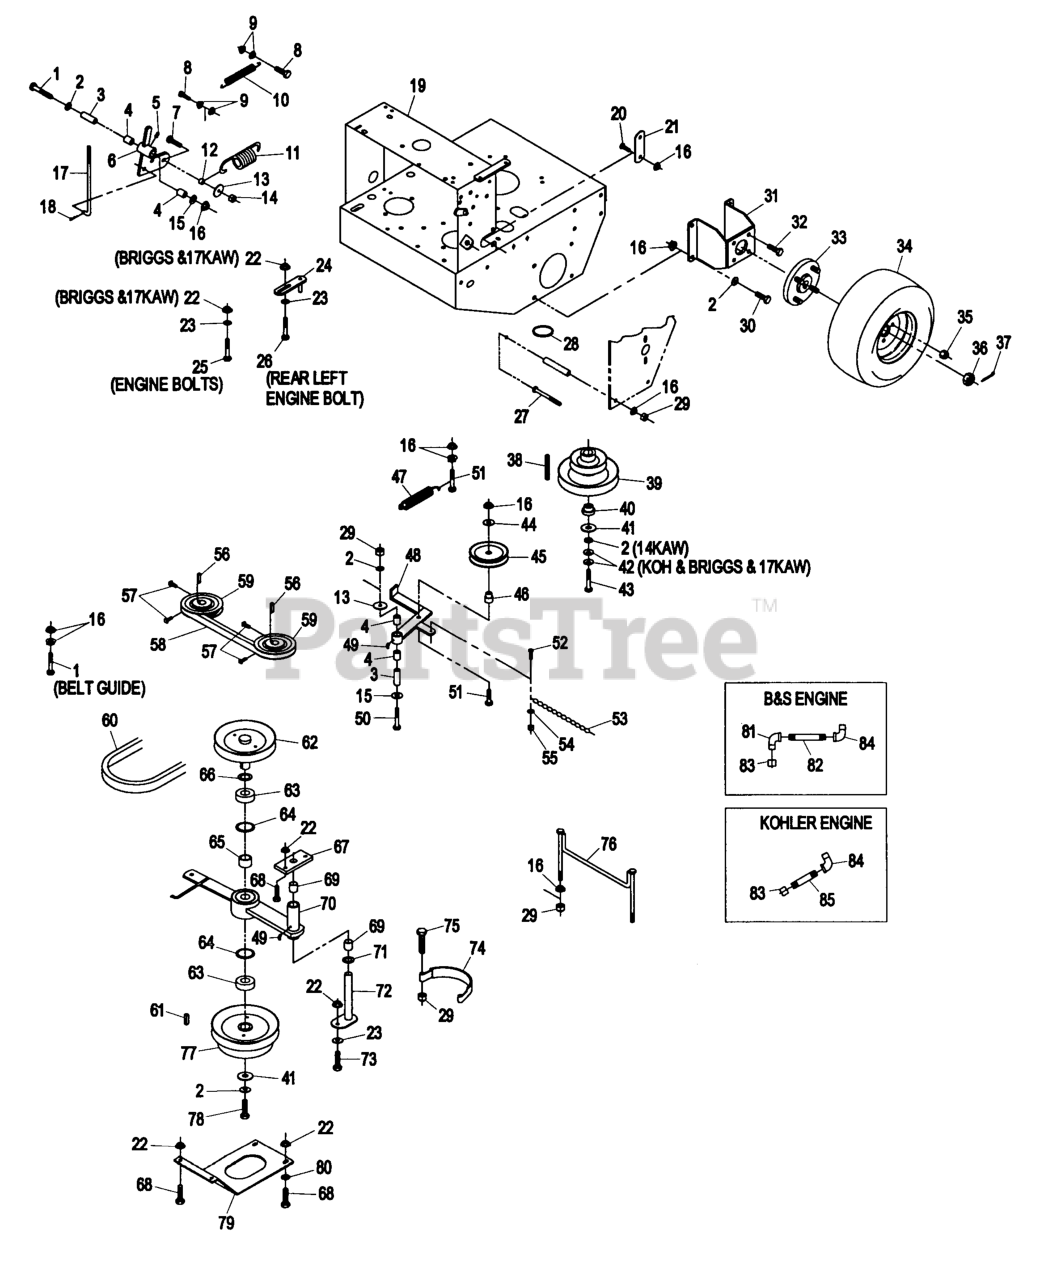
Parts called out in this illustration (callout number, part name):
3	BUSHING
4	SLEEVE-BEARING
10	SPRING,EXTENSION
11	SPRING,BELT TENSION
12	SPACER,CLUTCH ANCHOR
17	LINKAGE,LOWER
18	PIN-COTTER
21	ARM-LIFT, DECK
23	WASHER-SPRING
24	GUIDE-BELT
28	RING-SPLIT
31	WLD,MOTOR MOUNT 36
37	PIN-COTTER
38	KEY,MACH 1/4X1/4X2-5/8
39	SHEAVE,DRIVE
40	BUSHING,CLUTCH KEEPER
42	WASHER-SPRING
43	SCRW,CAP HH
46	BUSHING-IDLER
47	SPRING-EXTENSION
49	1481
52	SCREW-HSH
53	CHAIN-LINK, TWIST
57	SCREW-SET
59	SHEAVE ASM
60	BELT,BLADE CLUTCH
62	SHEAVE,6.13 W/SHAFT
63	BEARING,CLUTCH SHAFT
65	SPACER,CLUTCH BEARING
66	WASHER-SPACER
67	PLATE-CLUTCH PIVOT
69	SLEEVE,BEARING
71	WASHER-SPACER
72	WLD,PIN PIVOT
74	BAND,BRAKE BLADE
76	GUIDE - BELT
77	SHEAVE,6.13 W/HUB
78	SCRW,CAP HH
79	PLATE-GUARD
81	ELBOW-90 DEG
82	NIPPLE
83	CAP-HEX
84	FITTING-ELBOW-90
85	NIPPLE
